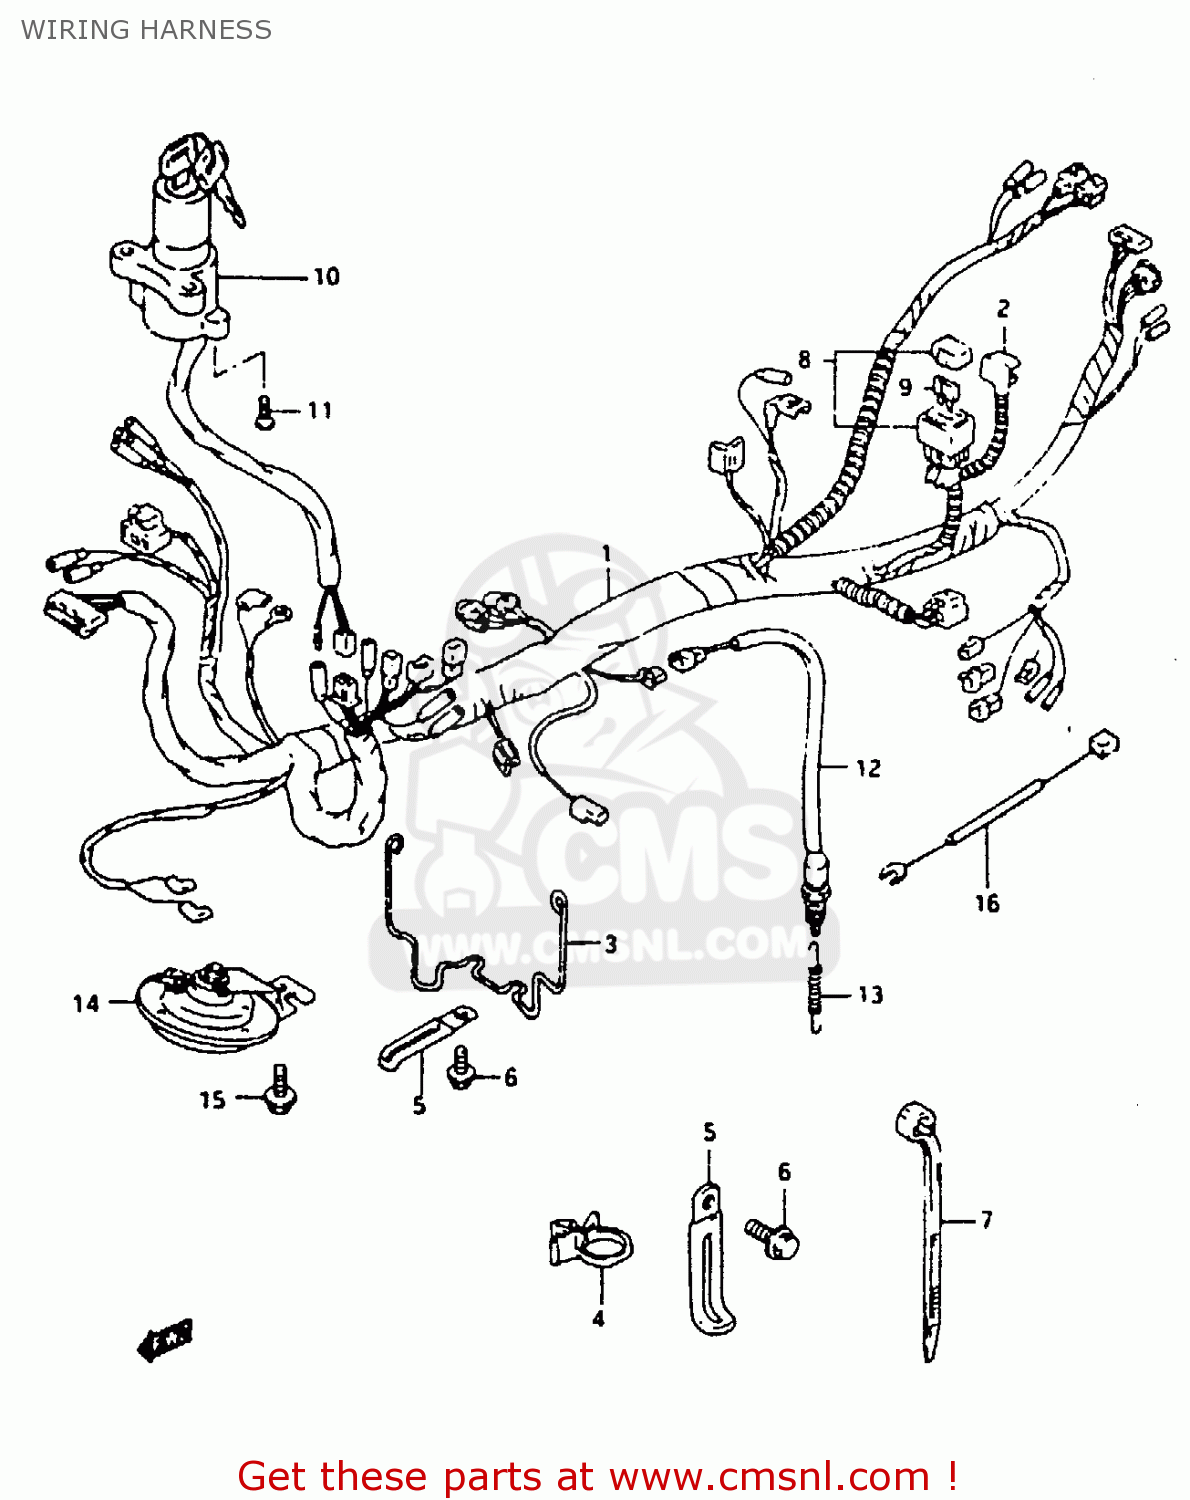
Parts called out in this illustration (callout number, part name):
1	HARNESS, WIRING
2	CAP,BATTERY PLUS
3	GUIDE, HARNESS
4	CLAMP
5	CLAMP
6	BOLT
7	CLAMP(L:95)
8	BOX ASSY,FUSE
9	FUSE(15A)
10	LOCK ASSY,STEERING
11	SCREW(6X18)
12	SWITCH ASSY,STOP LAMP
13	SPRING
14	HORN ASSY
15	BOLT
16	WIRE, NEUTRAL SWITCH LEAD
